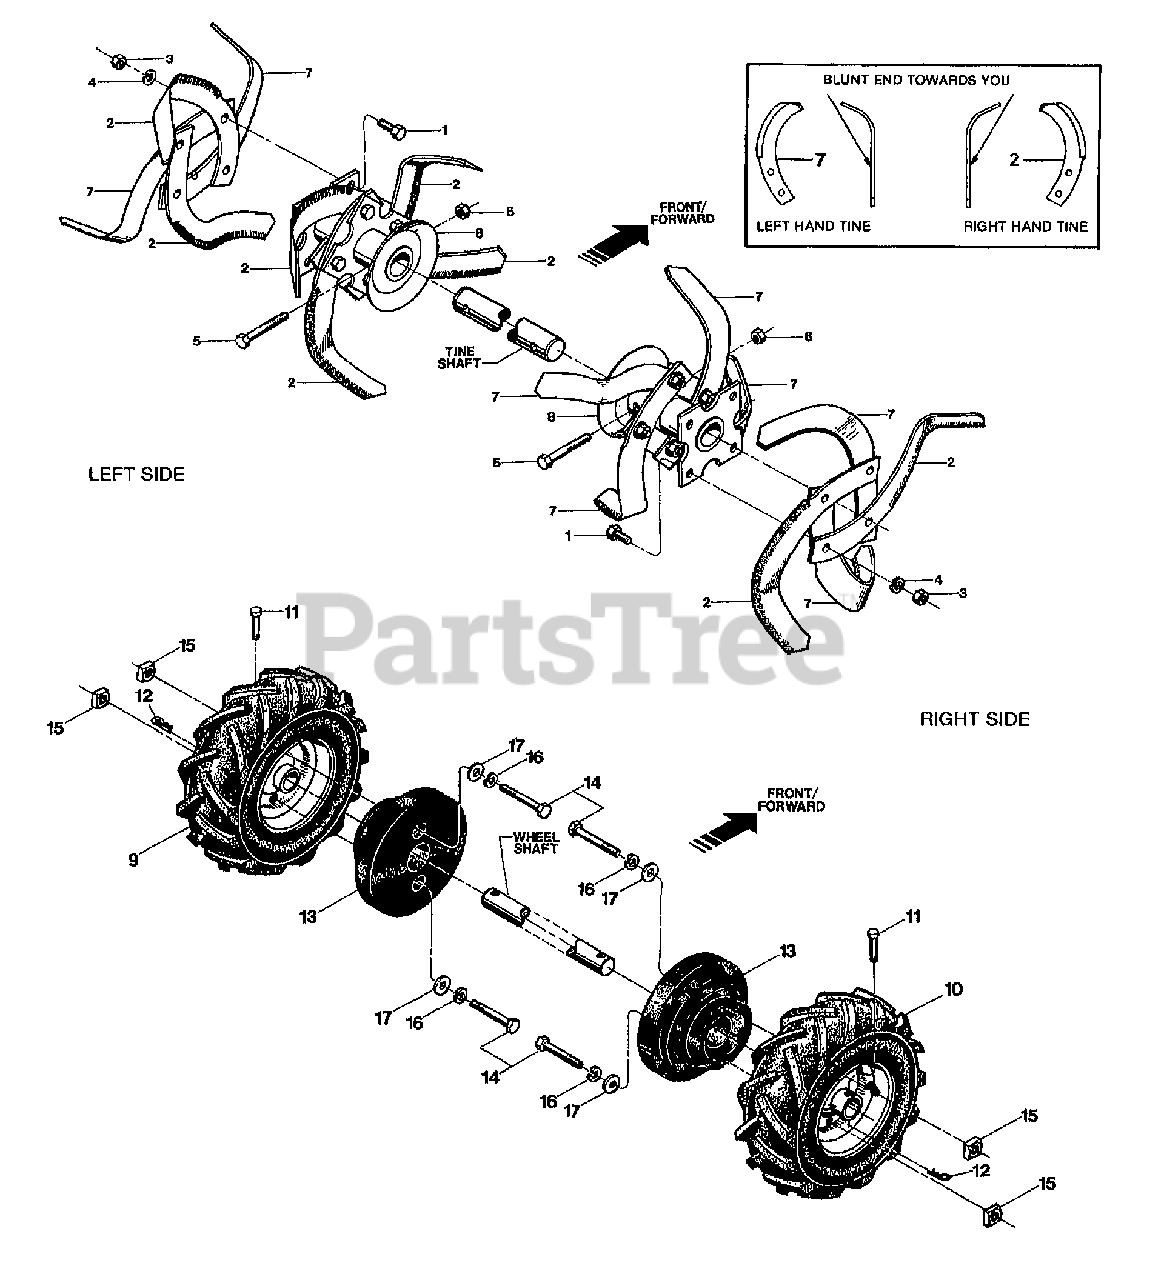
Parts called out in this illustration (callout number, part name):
1	SCR-HH 3/8-16X1.0 G5 ZP
1	SCR-HH 3/8-16X1-1/4" G5 ZP (1501004 & UP)
2	TINE-BOLO RT W/HDW
3	NUT-LOCK 3/8-16
4	WASHER-LK .375 @ DEPL
5	SCR-HH 3/8-16X2.00 G8
6	NUT-H/LK 3/8-16
7	TINE-BOLO LT W/HDW
8	WELD-TINE HOLDER ECONO (USE W/1.00" O.D. TINESHAFTS)
8	HOLDER-TINE ECONO RED (USE W/15/16" O.D. TINESHAFT)
9	ASSM-TIRE&WHEEL LH GRAY (15-20 LBS AIR REQ'D)
10	ASSM-TIRE&WHEEL RH GRAY (15-20 LBS AIR REQ'D)
11	PIN-CLEVIS
12	PIN-CLIP .08
13	WEIGHT-WHEEL
14	SCR-HH 3/8-16X3.0 G5 ZP
15	NUT-SQ 3/8-16
16	WASHER-LK .375 @ DEPL
17	WASHER-FLAT 3/8 SAE
